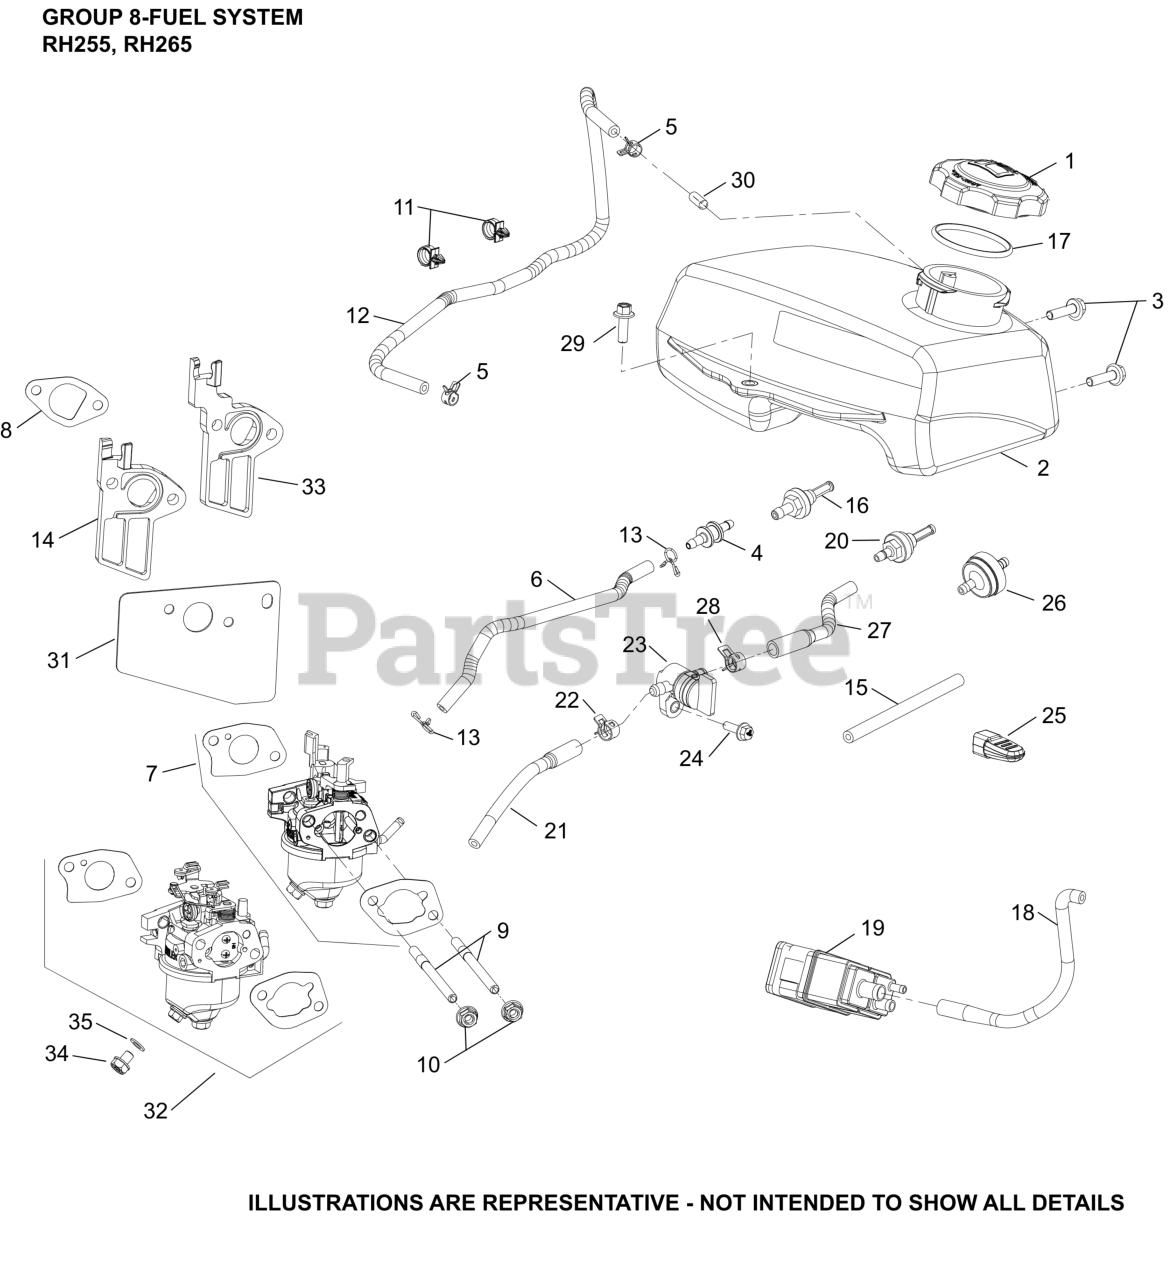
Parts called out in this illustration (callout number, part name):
1	CAP ASSEMBLY, FUEL
2	TANK, ASSEMBLY (EPA)
3	SCREW, M6 X 22
7	KIT,CARB (HUAYI)
8	KIT, INTAKE GASKET
9	STUD, CARBURETOR
10	NUT, HEX FLANGE (M6) - USE 14 100 16-S
10	NUT, HEX FLANGE LOCK (M6)
11	CLIP, FUEL HOSE
12	HOSE, EVAPORATIVE
13	CLAMP, FUEL HOSE
14	INSULATOR, CARBURETOR
17	SEAL, FUEL CAP- (#DSC)
18	HOSE PURGE, CARBON CANISTER TO A/C BASE
19	CANISTER ASSEMBLY, CARBON
20	FITTING, FUEL ASSY
21	HOSE, FUEL LOW-PERMEATION
22	CLAMP, HOSE (NON-CALIF)(#1423710S)
23	VALVE, FUEL SHUTOFF ASSEMBLY
24	SCREW, M5 X 16 M5 X 16
25	KNOB, CHOKE (YELLOW)-USE 18 536 11-S
29	SCREW, M6 X18
NI	KIT, CARBURETOR REPAIR (HUAYI)
NI	KIT, HIGH ALT (4000-8000 FT)
NI	KIT, CARB - HIGH ALTITUDE (ABOVE 8,000')
